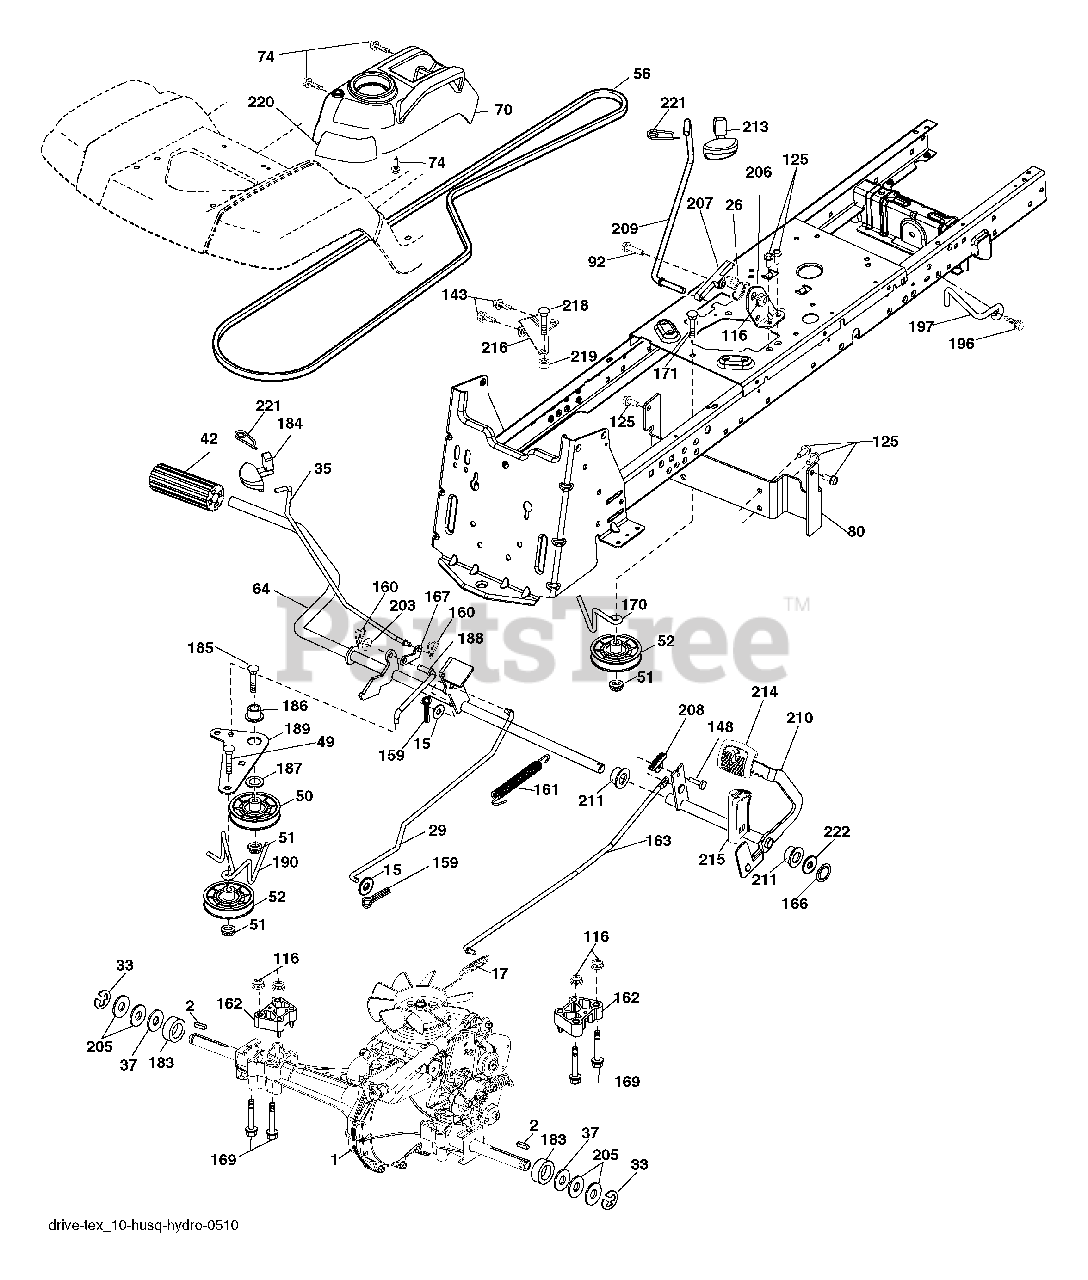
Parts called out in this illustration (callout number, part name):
2	Key 1/4 x 2.5
15	Washer 13/32 x 13/16 x 16 Ga.
17	Spring, Brake
26	Spring Return Cruise
29	Rod, Brake
35	Rod, Brake, Park
42	Cover, Foot Pedal
50	Pulley Idler Flat
51	Lock Nut 3/8-16
52	Idler V-Groove 910" Offset
56	V-Belt, Drive
64	Shaft Asm. Pedal Brake Control
70	Control Asm.
74	Screw 1/4 x 1/2
80	Bracket Strap Torque
92	Bolt Fin Hex 5/16-18 unc x 1.25
116	Nut Lock Hex Flange 5/16-18
125	Screw 5/16-18 x 3/4
143	Screw Thdrol 5/16-18 x 1/2
148	Screw 3/8-16 x 3/4
159	Pin Cotter 1/8 x 3/4
160	Retainer Clip
161	Spring, Return, Clutch
162	Spacer Transaxle
163	Rod Pedal Control
166	Nut Push .625
167	Latch Brake Parking
169	Bolt Hex Flghd 5/16-18 x 3.75
170	Keeper Belt Centerspan
183	Spacer Split
184	Handle Parking Brake
185	Bolt Rdhd Sqnk 3/8-16 x 2-1/2
186	Spacer Retainer
187	Washer
188	Link Clutch Ground Drive
189	Bellcrank Ground Drive
190	Keeper Bellcrank Ground Drive
196	Screw 3/8-16 x 1
197	Bracket Clutch Anti-Rotation
203	Washer 11/32 x 11/16 x 16 Ga.
206	Bracket Mount Latch Cruise
207	Latch Control Cruise
208	Gear Sector Control Cruise
209	Rod Control Cruise
210	Rocker Asm. Pedal Control
211	Bearing Nylon
213	Knob Control Cruise
214	Pedal Forward
215	Pedal Reverse
216	Bracket Pulley Idler
218	Bolt Fin Hex 5/16-18 unc x 1-1/4
219	Spacer Fender
220	Reflector RH
221	Retainer Spring Clip Handle
222	Washer Flat
